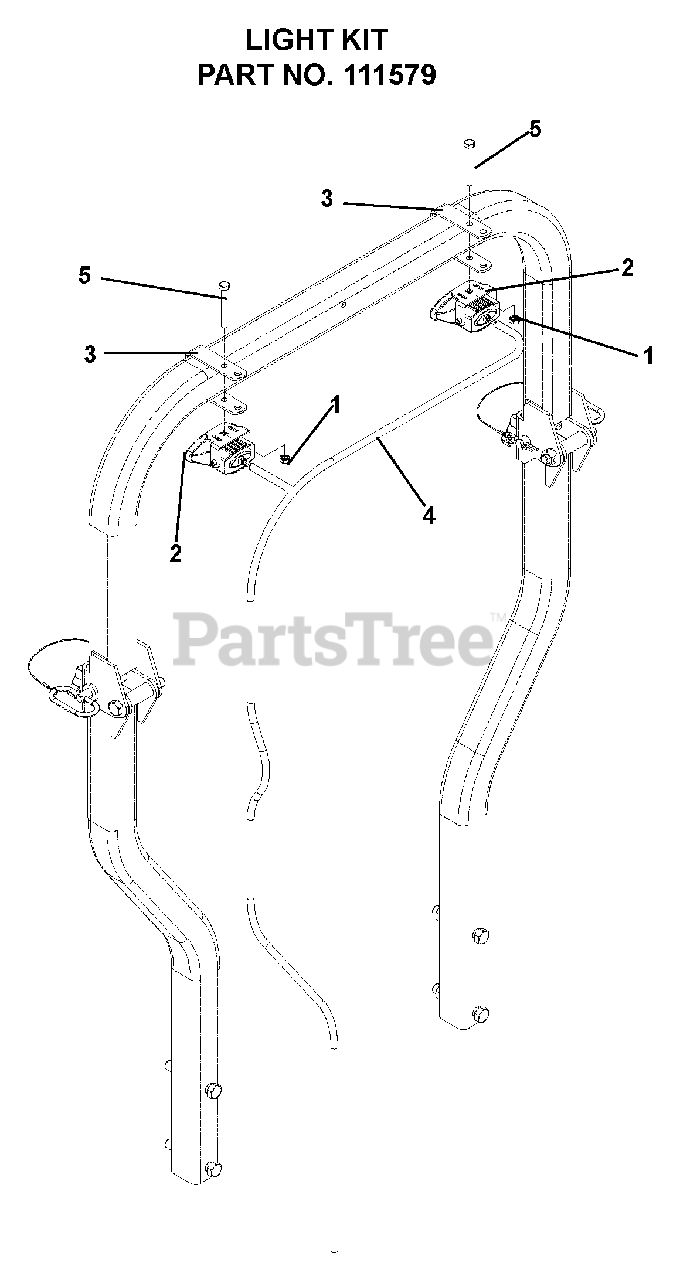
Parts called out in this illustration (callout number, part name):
1	NUT, 5/16-18, JAM
2	LIGHT W/BRACKET & HARDWARE
3	LIGHT MOUNTING BRACKET
4	LIGHT HARNESS
5	HCS, 5/16-18 X 2 1/2, GR5
111579	Light Kit (Accessories)
